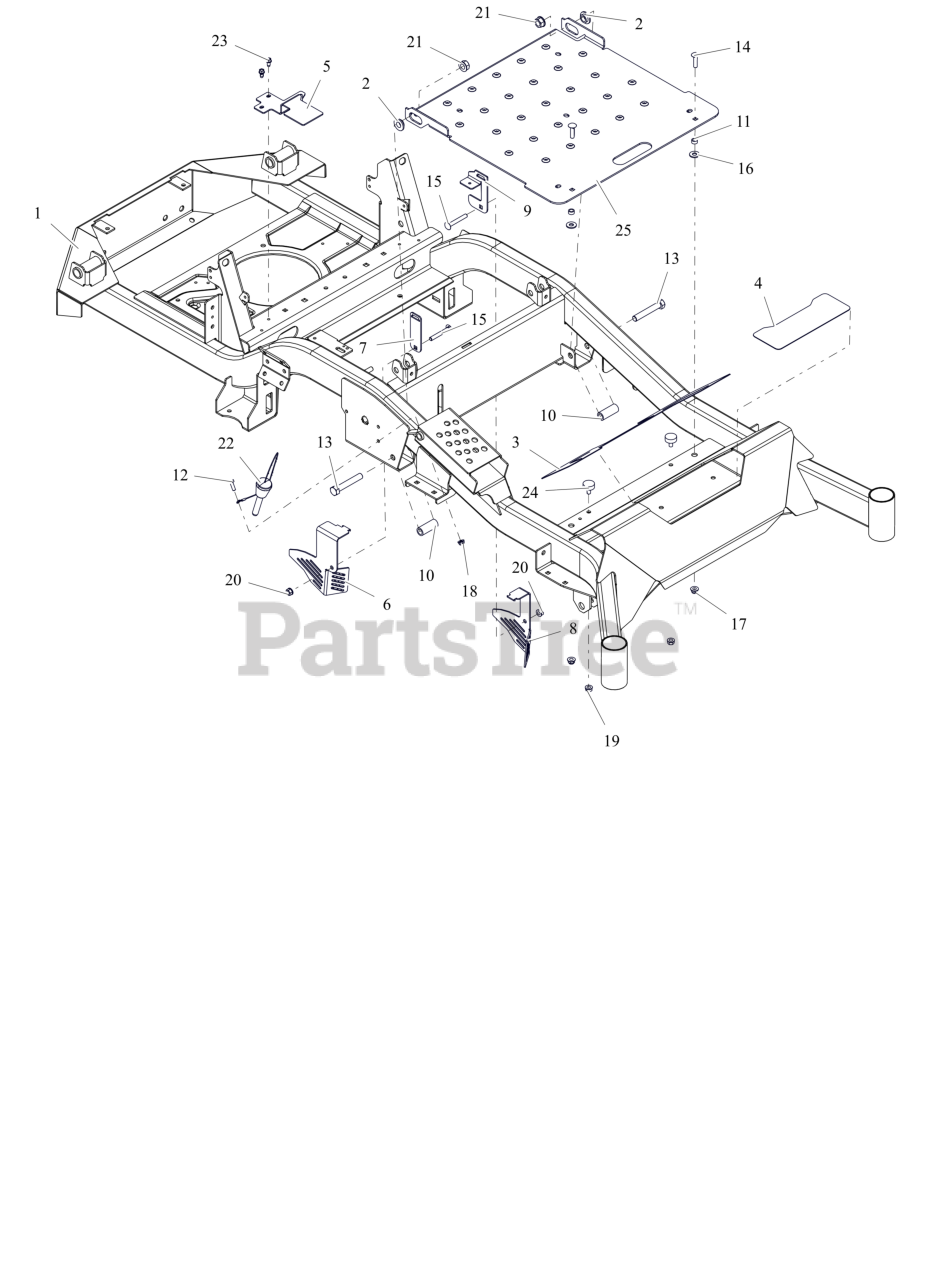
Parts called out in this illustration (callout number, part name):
1	WLDMT, MAIN FRAME -APEX 44-52 (ORANGE)
2	BSHG-FLG .515X.750X.395X1.120
3	GRIP, FRONT
4	GRIP, STEP
5	GUARD, TRANSAXLE FAN RH (BLACK)
6	GUARD, TRANSAXLE FAN - RH
7	BRKT, TRANSAXLE FAN GUARD
8	BRKT, TRANSAXLE FAN GUARD-LH
9	MOUNT, TRANSAXLE GUARD
10	SPACER, .515X.75X1.83
11	BSHG-SLV .344 X .500 X .260
12	BLT, HEX .25-20X.75 G5 ZCC
13	BLT, HEX .50-13X3.00 G5 ZCC
14	BLT, RHSSN.31-18X1.25 G5 ZCC
15	BLT, RHSSN.31-18X2.25 G5 ZCC
16	WSHR,FLT .375X.875X.083 ZCC
17	NUT,LK-NYL-FLG .31-18 G5ZC120
18	NUT,NYL-FLG .25-20 GF ZCC
19	NUT,SPNLK-FLG .31-18 G5 ZCC
20	NUT,LK-CTR-FLG .31-18 GF ZCC
21	NUT-LK-TOP-FLG .500-13 GF ZCC
22	PIN, MAGNETIC .50X2.50
23	SCR-TAP .25-20X.50 HWH ZCC
24	BUMPER, RUBBER
25	PANEL, ACCESS
